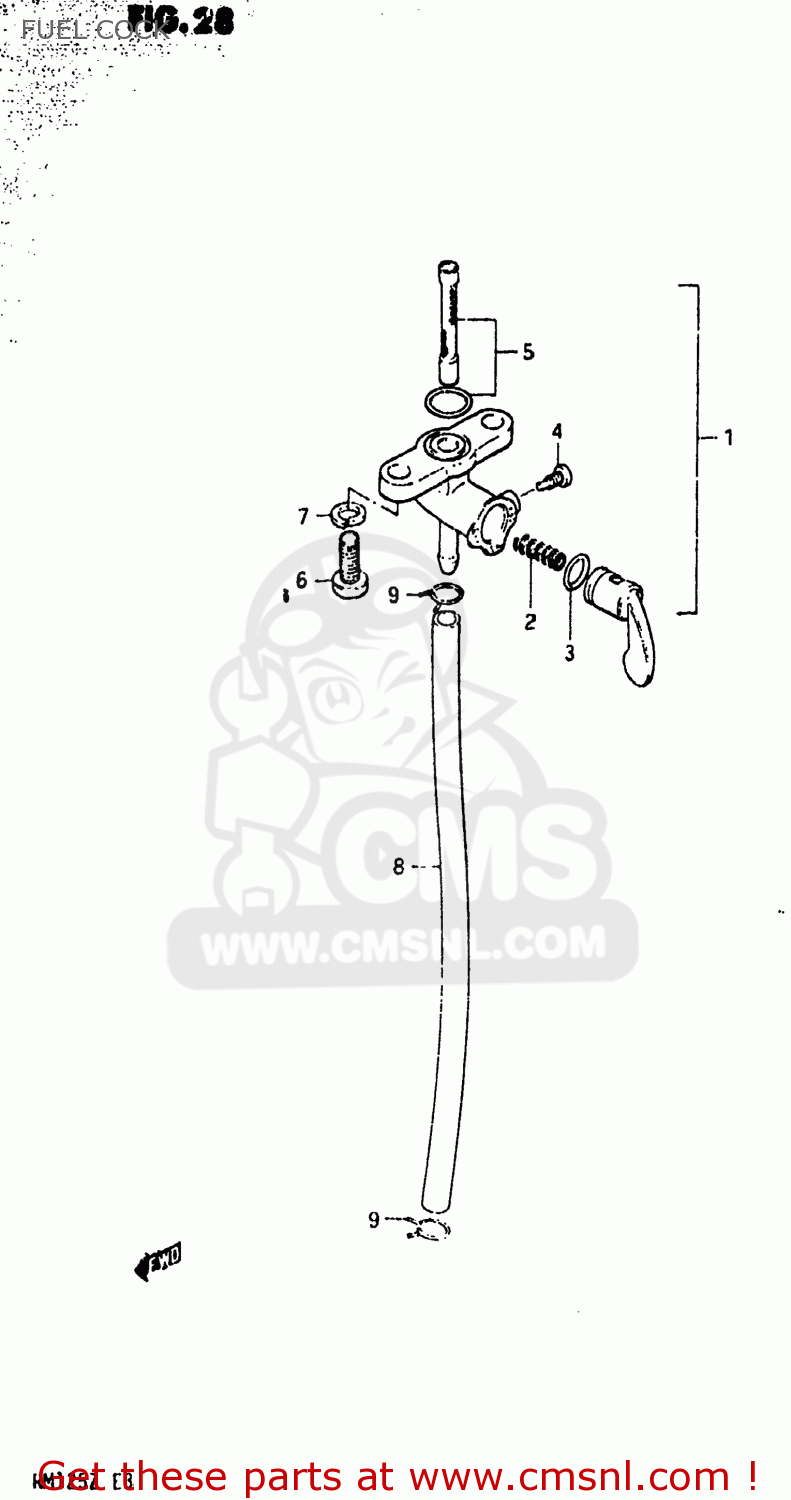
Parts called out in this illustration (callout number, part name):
1	COCK ASSEMBLY,FUEL
2	SPRING,FUEL COCK VALUE
3	O RING,LEVER
4	SCREW
5	FILTER SET FUEL
6	SCREW
7	LOCK WASHER
8	HOSE
9	CLIP
